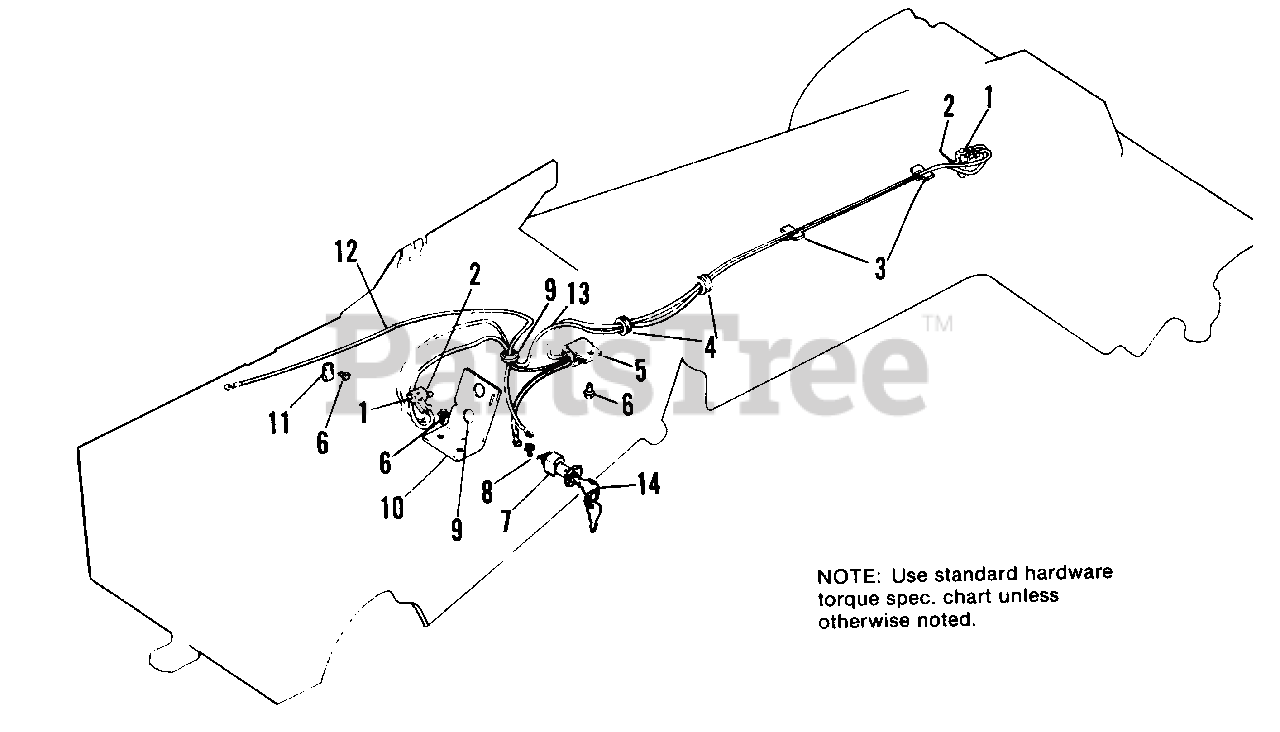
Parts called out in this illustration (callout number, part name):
1	SWITCH, Safety
2	PALNUT
3	CLIP, Wire
5	INTERLOCK, Ignition
6	SCREW, Hex, Washer Hd., Taptite, 1/4-20 x 3/8
10	SUPPORT, Switch
14	KEY & RING ASSY.
